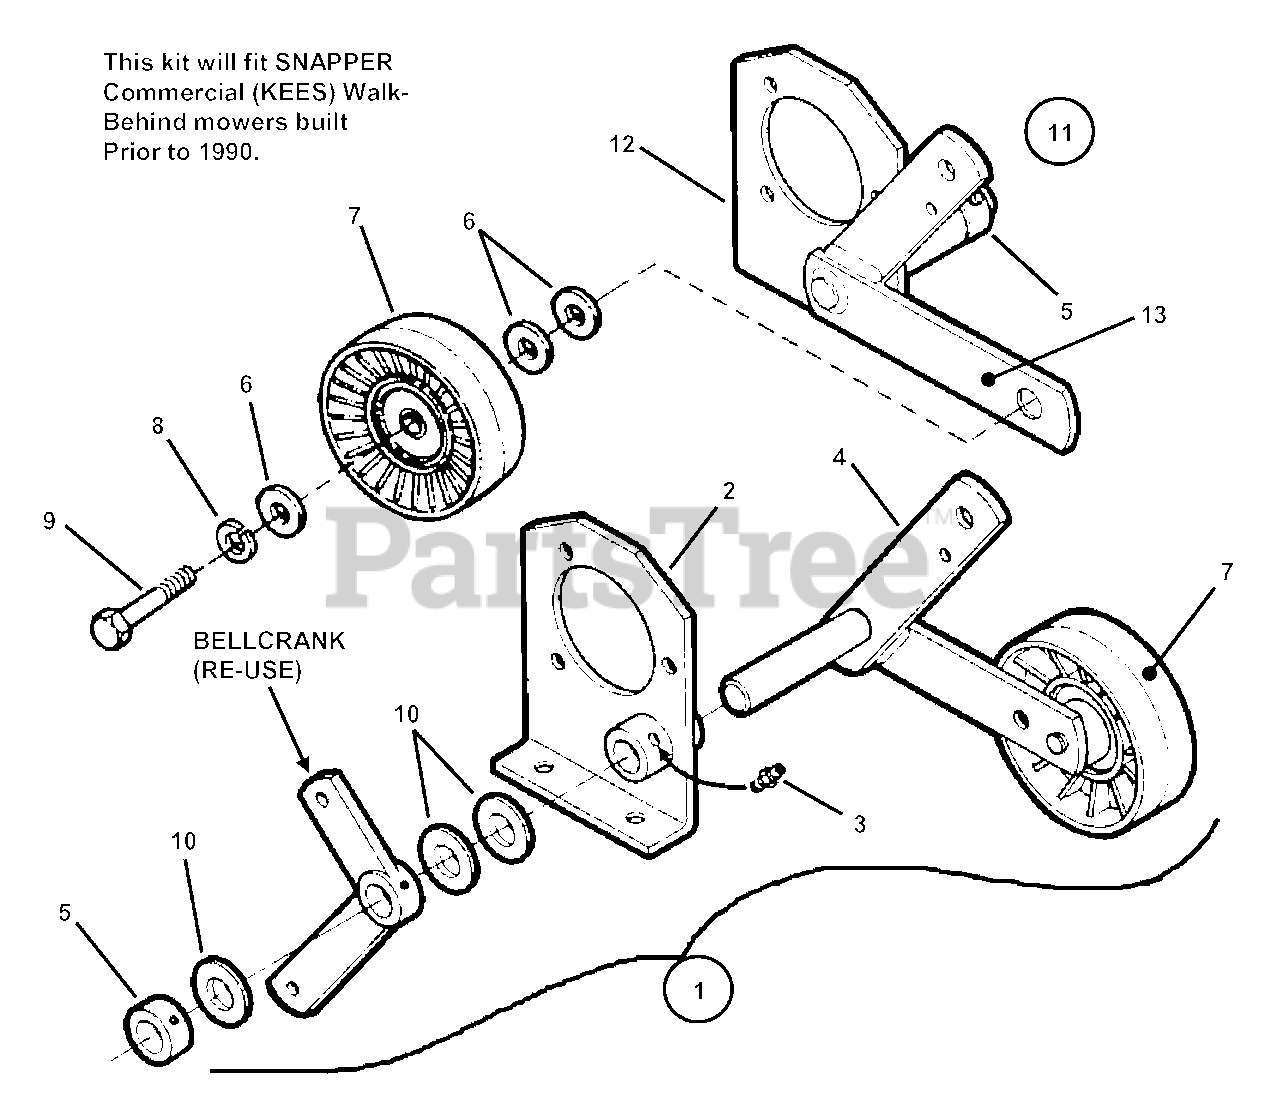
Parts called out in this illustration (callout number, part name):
1	ASSEMBLY, Left Support Bracket
2	WELDMENT, Left Bearing Support
3	FITTING, Lube, 1/4-28, Straight
4	WELDMENT, Traction, Left
5	COLLAR, Shaft
6	WASHER, 3/8" Flat
7	IDLER PULLEY
8	WASHER, 3/8" Split Lock
9	SCREW, 3/8-24 x 1-3/4" Hex Head Cap, Grade 5
10	BUSHING, Machine
11	ASSEMBLY, Right Support Bracket
12	WELDMENT, Right Support Bracket
13	WELDMENT, Traction, Right
